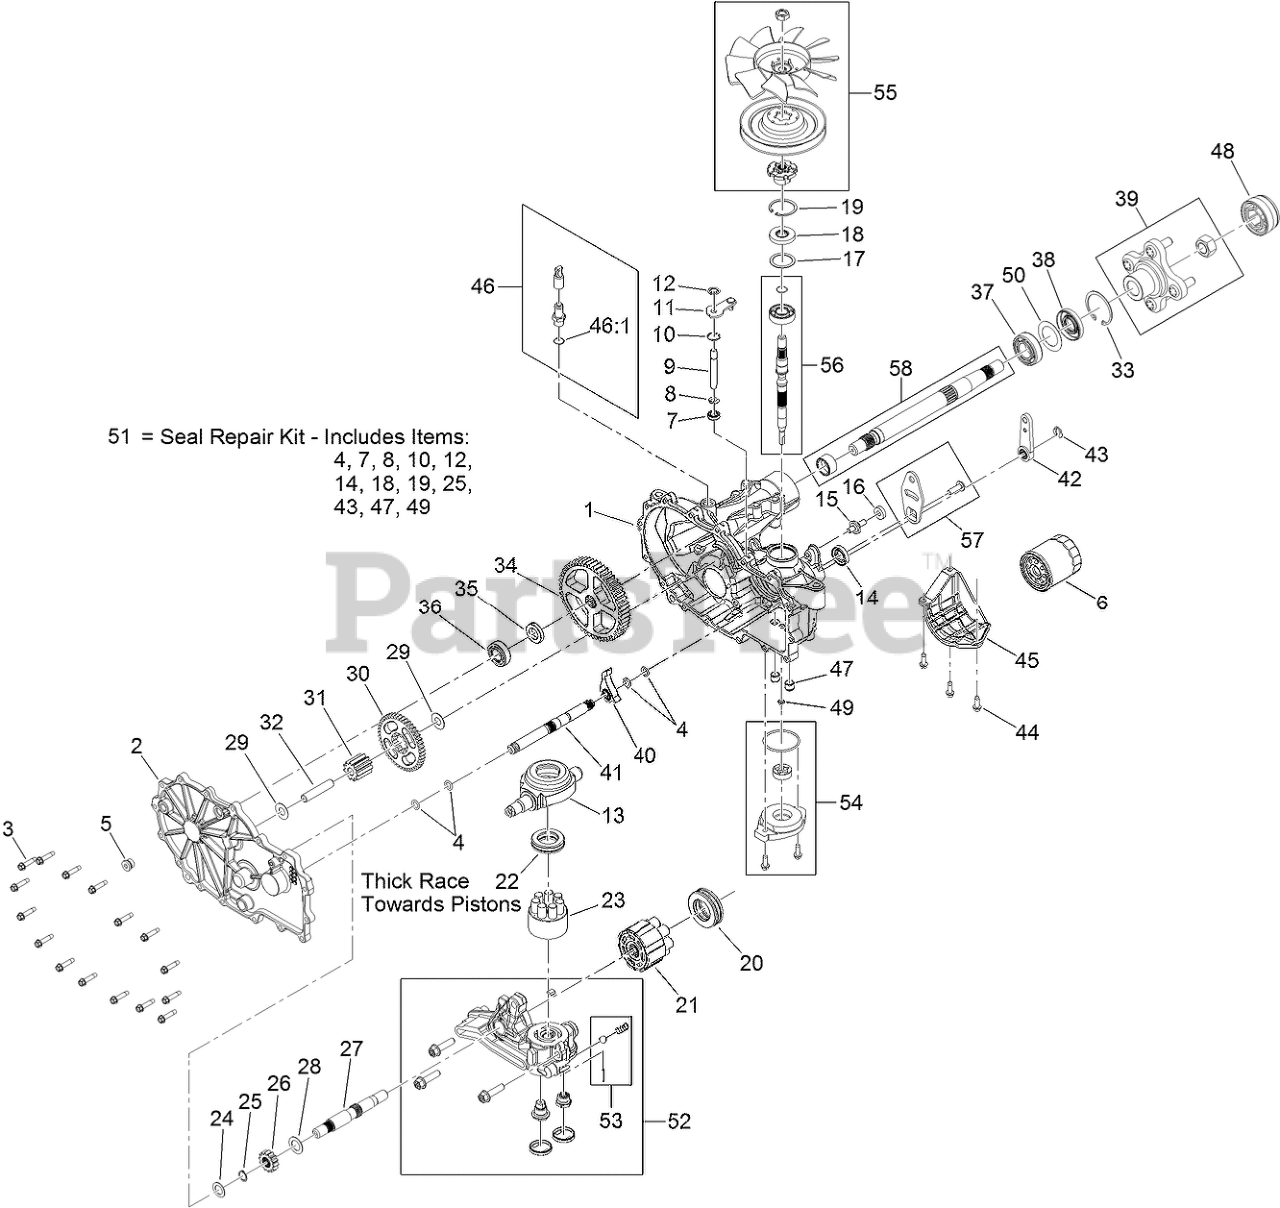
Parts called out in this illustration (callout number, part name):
1	LH MAIN HOUSING KIT
2	LH SIDE COVER KIT
3	SCREW-HHF
4	O-RING
5	PLUG-THREAD, STRAIGHT
6	ELEMENT-OIL FILTER, HYD
7	SEAL-LIP
8	RING-RETAINING, EXTERNAL
9	ROD-BYPASS
10	RING-RETAINING, INTERNAL
11	ARM-BYPASS
12	RING-RETAINING, EXTERNAL
13	SWASHPLATE-TRUNNION
14	SEAL-LIP
16	PUCK-FRICTION
17	SPACER
18	SEAL-LIP
19	RING-RETAINING
20	BEARING-THRUST
21	MOTOR CYLINDER BLOCK KIT
22	BEARING-THRUST
23	PUMP BLOCK ASM
24	WASHER-FLAT
25	RING-RETAINING
26	GEAR-14T
27	SHAFT-MOTOR
28	WASHER
29	WASHER
30	GEAR-45T
31	GEAR-11T
32	PIN-JACKSHAFT
33	RING-RETAINING
34	GEAR-54T
35	SPACER
36	BEARING-BALL
37	BEARING-BALL
39	HUB KIT
40	PAWL-BRAKE
41	SHAFT-BRAKE
42	HANDLE-BRAKE
43	RING-RETAINING, EXT
45	GUARD-FILTER, LH
46	ADAPTER-STRAIGHT
46:1	O-RING
47	TUBE-CONNECTING
48	COVER-NUT, AXLE
49	SEAL-GEROTOR
50	SPACER
51	SEAL KIT
52	LH CENTER SECTION CHARGE KIT
53	CHARGE RELIEF KIT
54	CHARGE KIT
55	FAN AND PULLEY KIT
56	INPUT SHAFT KIT
57	CONTROL ARM KIT
58	AXLE SHAFT KIT
